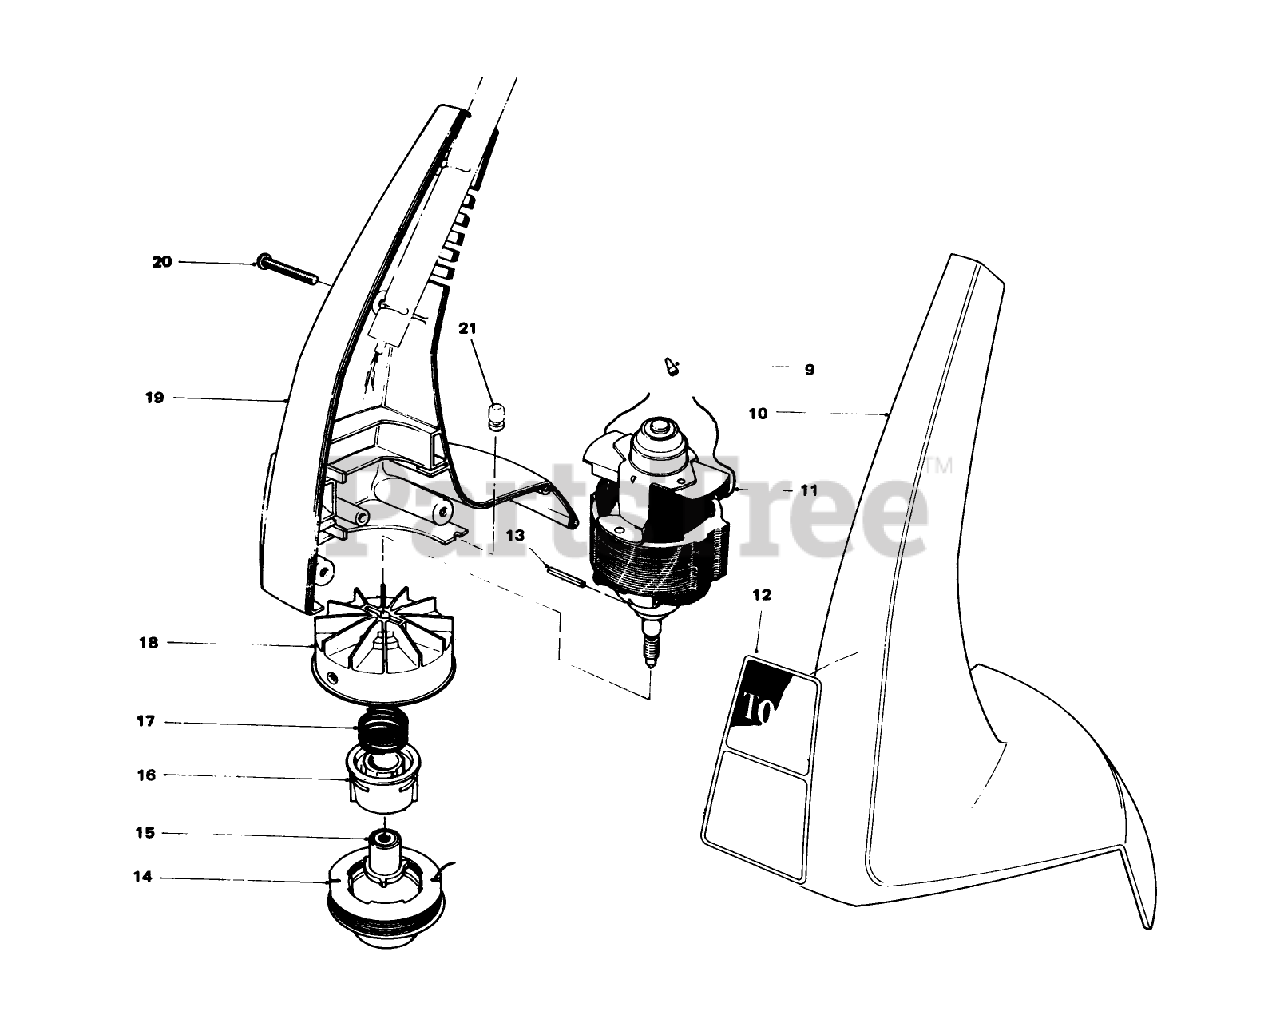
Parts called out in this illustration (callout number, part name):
9	CONNECTOR WIRE JOINT
10	Housing L.H.
11	Motor
12	DECAL 900
13	COIL PIN
14	Prewound Spool
15	Driver
16	CORE - SPOOL
17	SPRING-COMPRESSION
18	FAN HUB ASM
19	Housing R.H.
20	Screw
21	GROMMET
